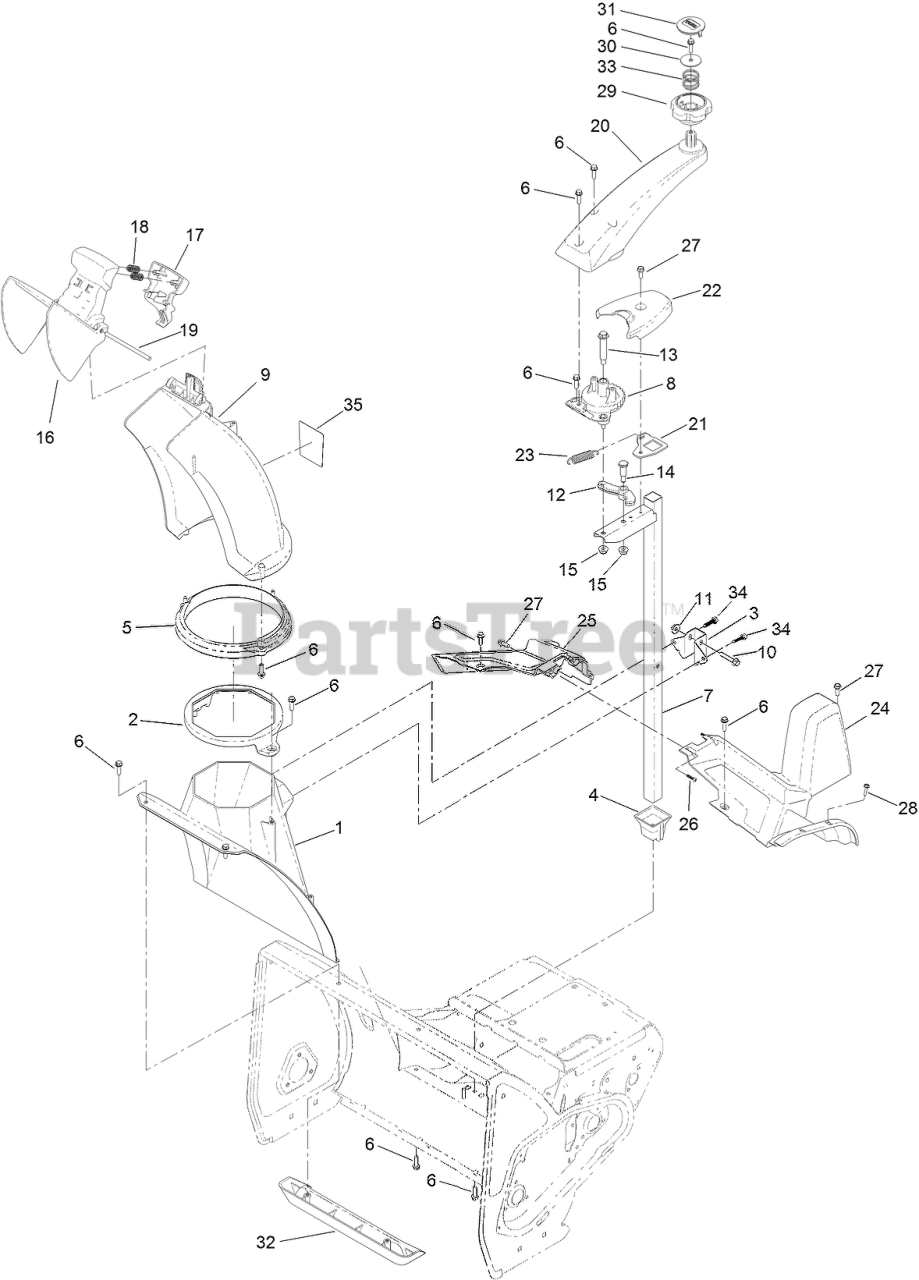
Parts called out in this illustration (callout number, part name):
1	CHUTE-LOWER
2	GUIDE-CHUTE
3	BRACKET-POST, SUPPORT (CHUTE)
4	RETAINER- POST, CHUTE
5	RING-CHUTE
6	SCREW-HWH
7	POST-CHUTE, MANUAL
8	GEAR-CHUTE, MANUAL
9	CHUTE-DISCHARGE
10	SCREW-HHF
11	NUT-HEX FLG
12	LATCH-CHUTE
13	BOLT-SHOULDER
14	SCREW-SHOULDER
15	NUT-HF, NI
16	DEFLECTOR-CHUTE
17	TRIGGER-DEFLECTOR
18	SPRING-COMPRESSION
19	ROD-COVER
20	HANDLE-CHUTE, MANUAL
21	SUPPORT-SPRING
22	COVER-SPRING
23	SPRING-EXTENSION
24	SHROUD-UPPER, LH
25	SHROUD-LOWER, RH
26	SCREW-PPH
27	SCREW-HWH
28	SCREW-HWH
29	KNOB-CONTROL, CHUTE
30	WASHER-FLAT
31	INSERT-KNOB
32	KICKER-HOUSING
33	SPRING-COMPRESSION
34	SCREW-FLANGE, PLASTIC
